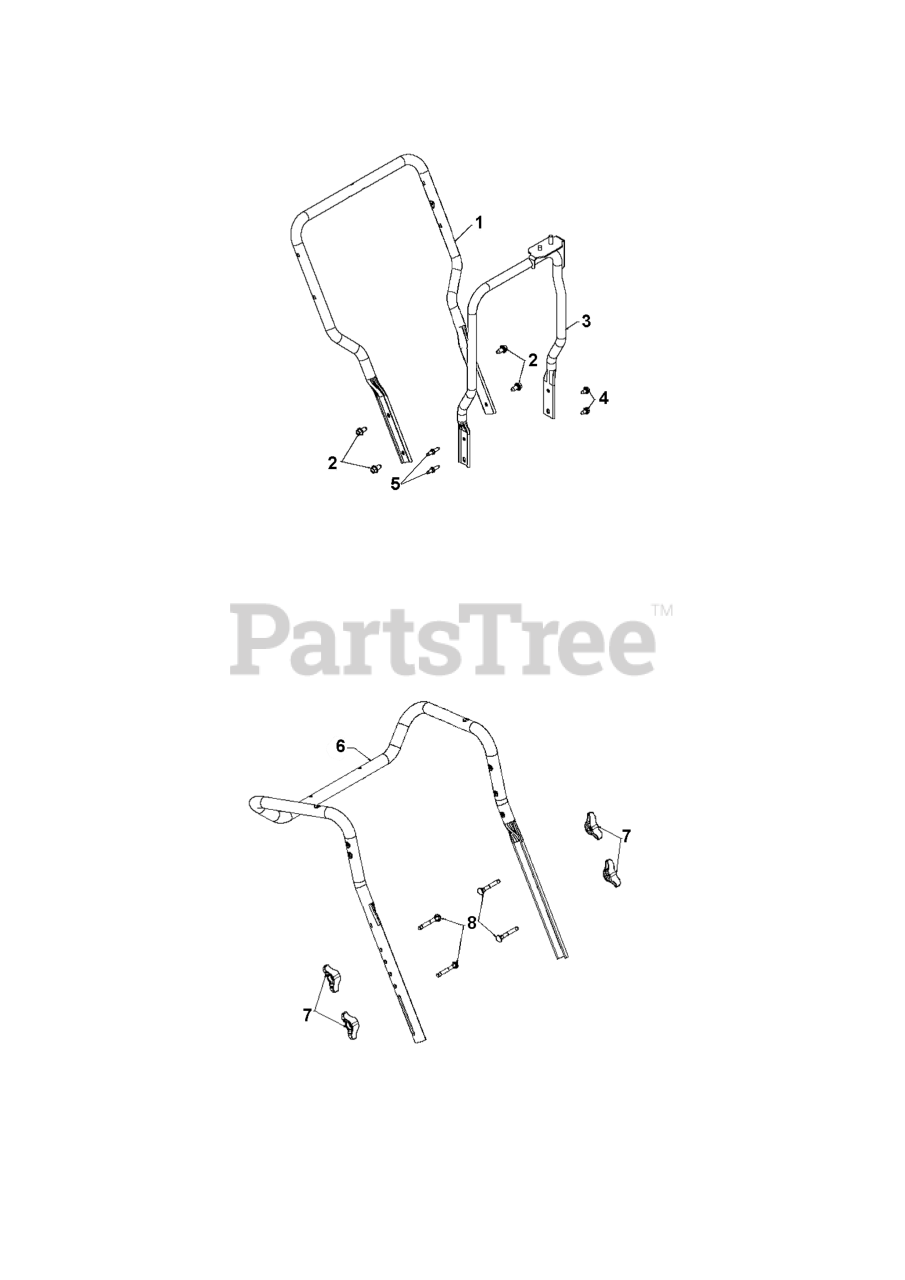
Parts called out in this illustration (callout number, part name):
1	HANDLE.LOWER.498
2	SCREW, 3/8-16X3/4
3	SUPPORT WELDMENT, CHUTE PAINTE
4	BOLT.5/16HEX.WHS.HD
5	STUD BOLTED HEX HEAD
6	HANDLE.UPPER.498
7	KNOB, DEFLECTOR
8	BOLT.CARRIAGE.5/16-18 X 2.25
